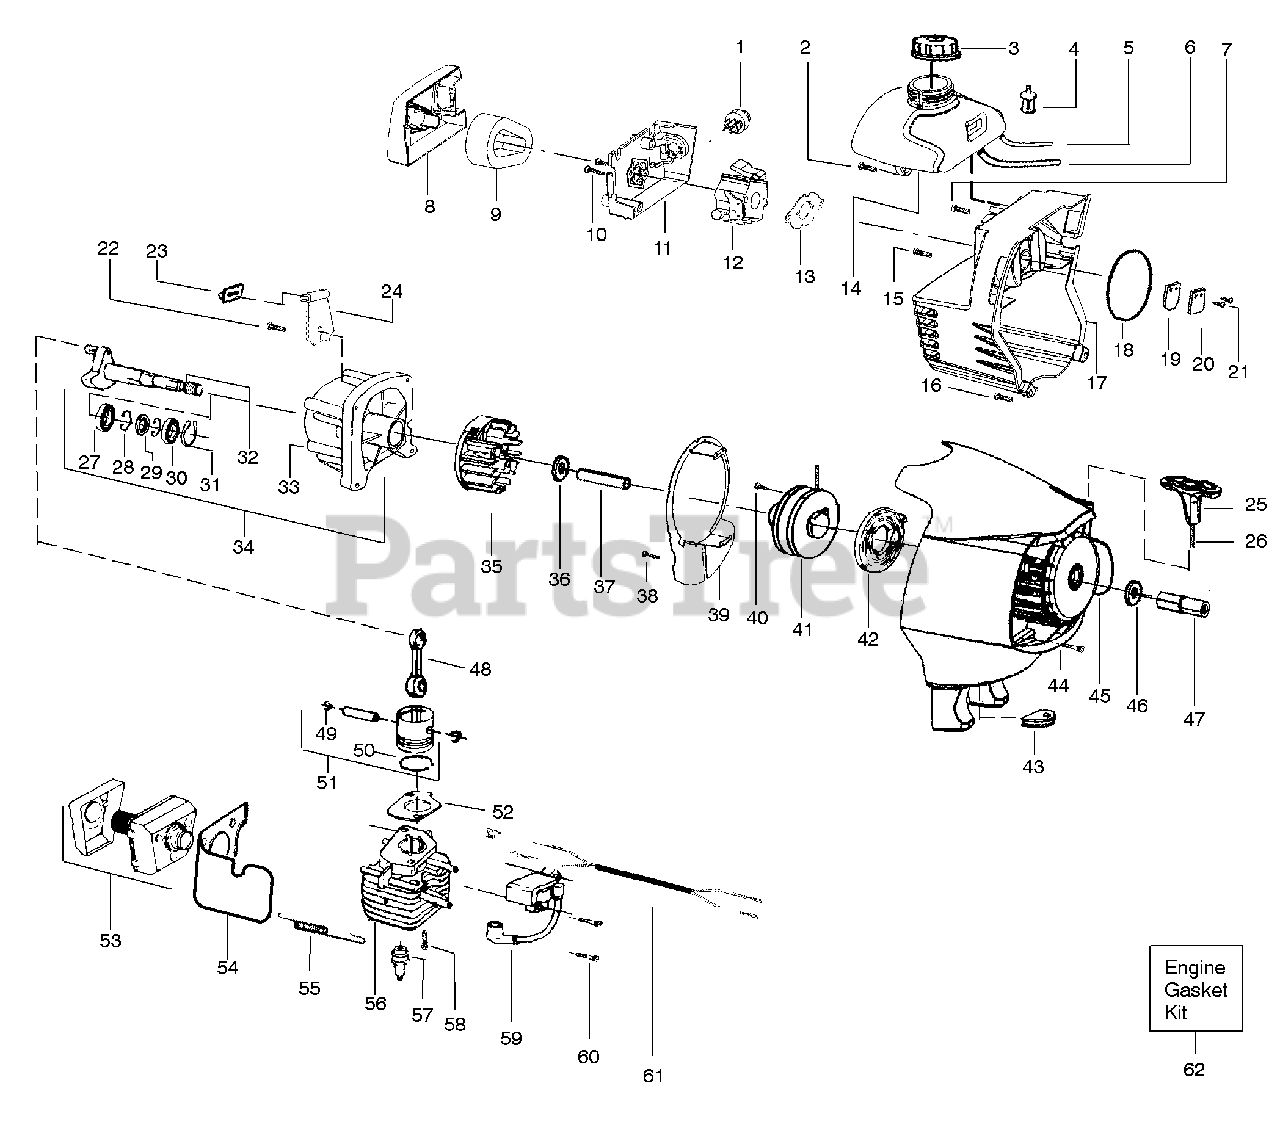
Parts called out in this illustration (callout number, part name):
1	Bulb-purge
2	Screw-tank
3	Assy-Fuel cap
4	Assy-Fuel pick-up
5	Kit-Fuel line
6	Kit-Fuel/Purge line
8	Cover-Air box
9	Filter-Air
10	Screw-carb.
12	Kit-Assy carb. (WT-618)
12	Kit-Assy carb. (WT-627)
13	Gasket-Carb.(kit)
14	Assy-Fuel tank
15	Screw-crankcase
16	Screw-shrd to f/hsg.
18	O-ring-c/case (kit)
19	Valve-reed
20	Stop-reed
21	Screw-reed valve
22	Screw-tank retainer
23	Isolator-fuel tank
24	Ret.-fuel tank
25	Handle-starter
26	Kit-Rope
27	Bearing-inner
28	Retainer
30	Bearing-outer
31	Retainer-crankshaft
32	Assy-crankshaft
33	Assy-crankcase
34	Assy-c'case/c'shaft
35	Kit - Assy.-Flywheel
38	Screw-baffle
39	Plate-baffle
40	Screw-rope
41	Kit-pulley
42	Spring-starter
44	Screw-F/hsg
45	Housing-Fan w/eyelet
47	Coupling-drive
48	Assy-Connecting rod
49	Retainer-piston pin
50	Ring-Piston
51	Kit-Piston
52	Gasket-Cylinder (kit)
53	Kit-Muffler
54	Heat shield/air dam
55	Spring-muffler
56	Kit-Cylinder
57	Spark plug (RCJ-6Y)
58	Bolt-Cylinder
59	Module-Ignition
60	Screw-module
61	Assy-Rear wire
62	Kit-Gasket
